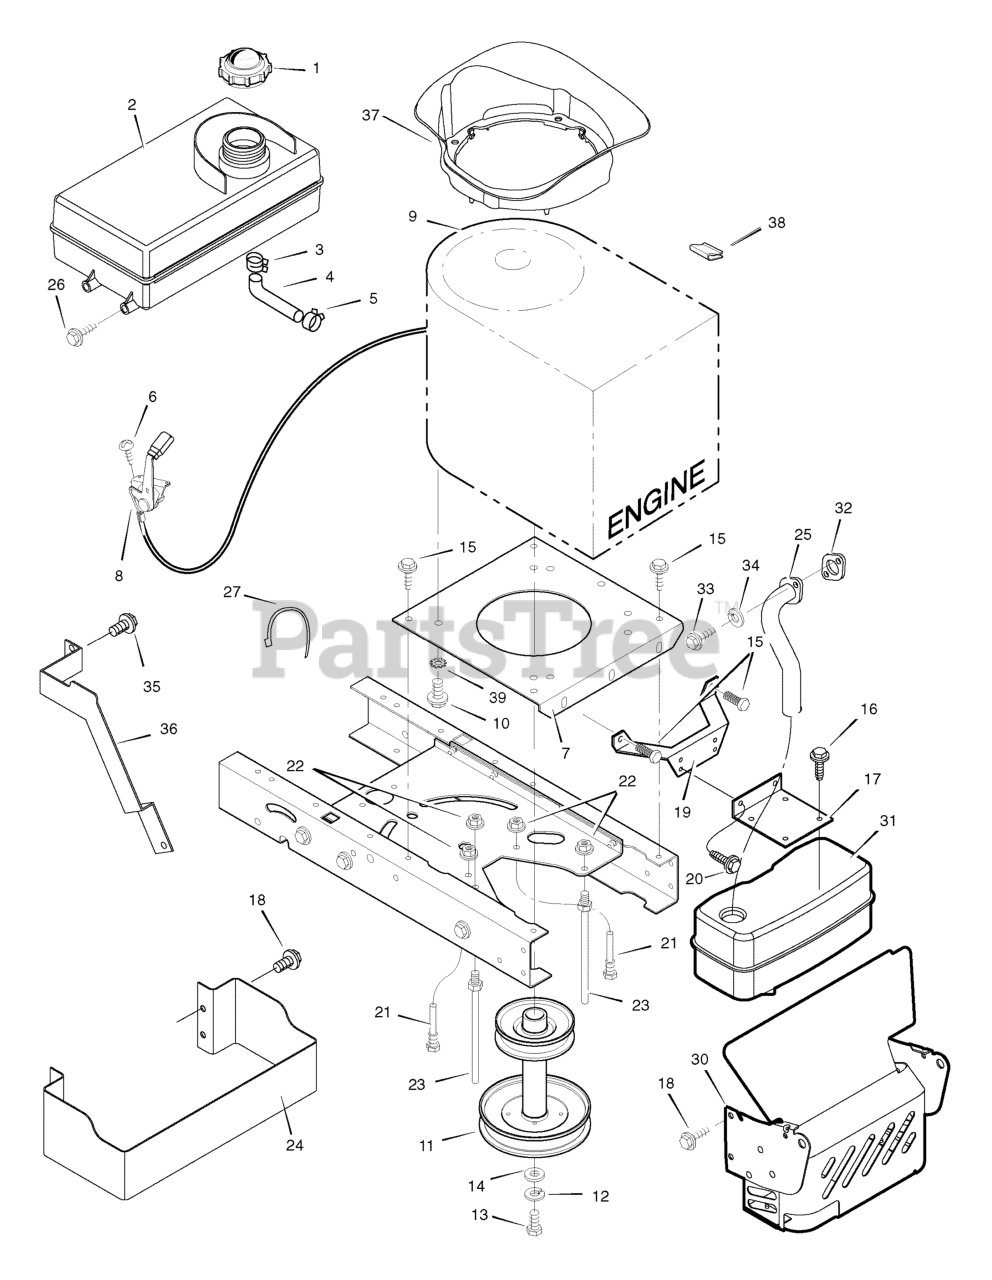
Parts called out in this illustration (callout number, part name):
1	Fuel Cap
2	TANK, Fuel 1.4 Gal.
3	Hose Clamp
4	Fuel Line (Must cut to length)
5	Hose Clamp
7	PLATE, Engine
8	THROTTLE CONTROL
9	ENGINE, Briggs & Stratton *
10	BOLT, Engine Mount
11	STACK PULLEY ASSEMBLY
12	LOCKWASHER
13	BOLT, Hex
17	BRACKET, Muffler
19	BRACKET, Muffler Mount
21	GUIDE, Belt
22	NUT, Flange
23	GUIDE, Belt
24	GUARD, Heat Shield
25	EXHAUST TUBE, Single
27	TIE, Strap, 5.38 Long
30	SHIELD, Heat
31	MUFFLER
32	GASKET, Exhaust
34	WASHER
35	BOLT, Washer Hex Head
36	GUARD, Exhaust Pipe
37	PLENUM, X1 M28/31
39	WASHER, 3/8-5/8 Star
40	CLIP, Wire Adhesive
